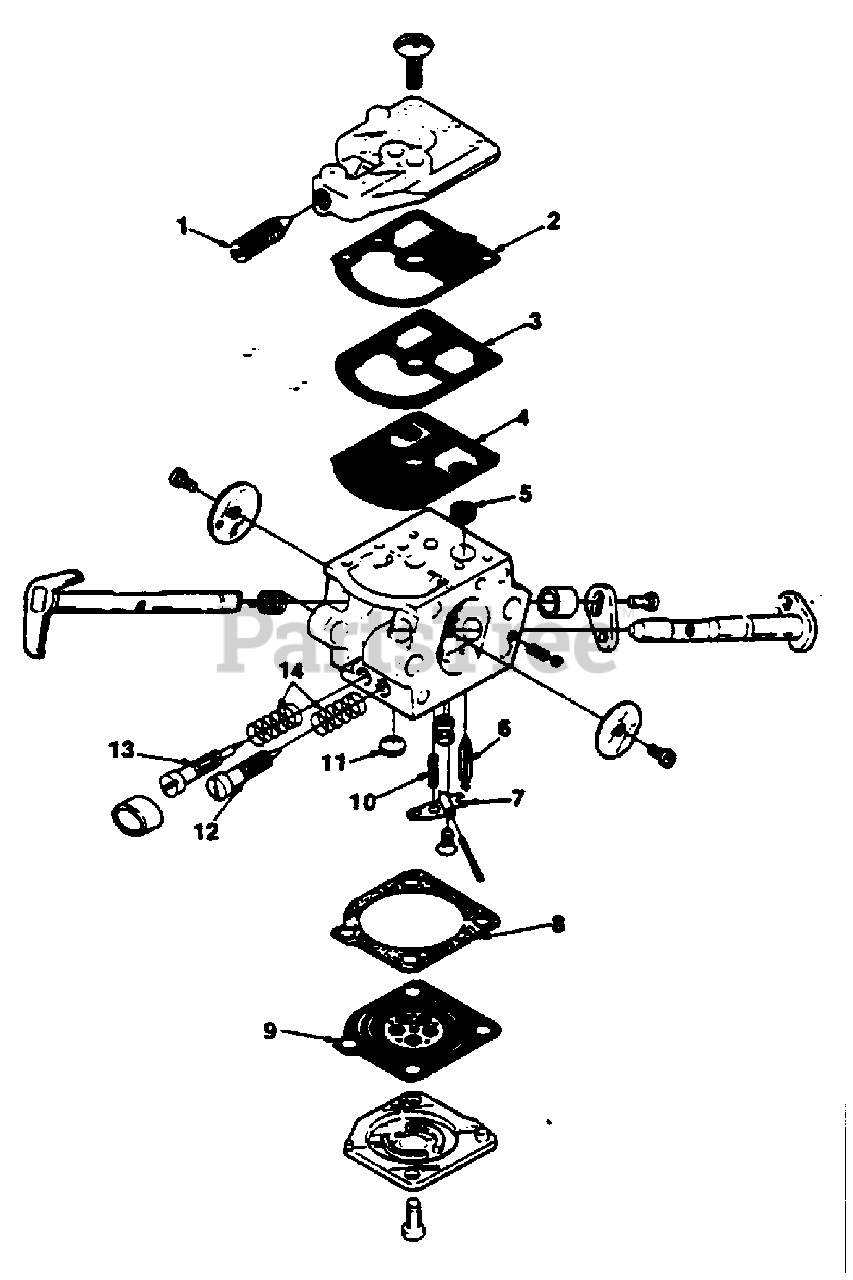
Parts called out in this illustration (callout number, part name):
1	REPAIR KIT
2	REPAIR KIT
3	REPAIR KIT
4	REPAIR KIT
5	REPAIR KIT
6	REPAIR KIT
7	REPAIR KIT
8	REPAIR KIT
9	REPAIR KIT
10	REPAIR KIT
11	REPAIR KIT
12	REPAIR KIT
13	REPAIR KIT
14	REPAIR KIT
